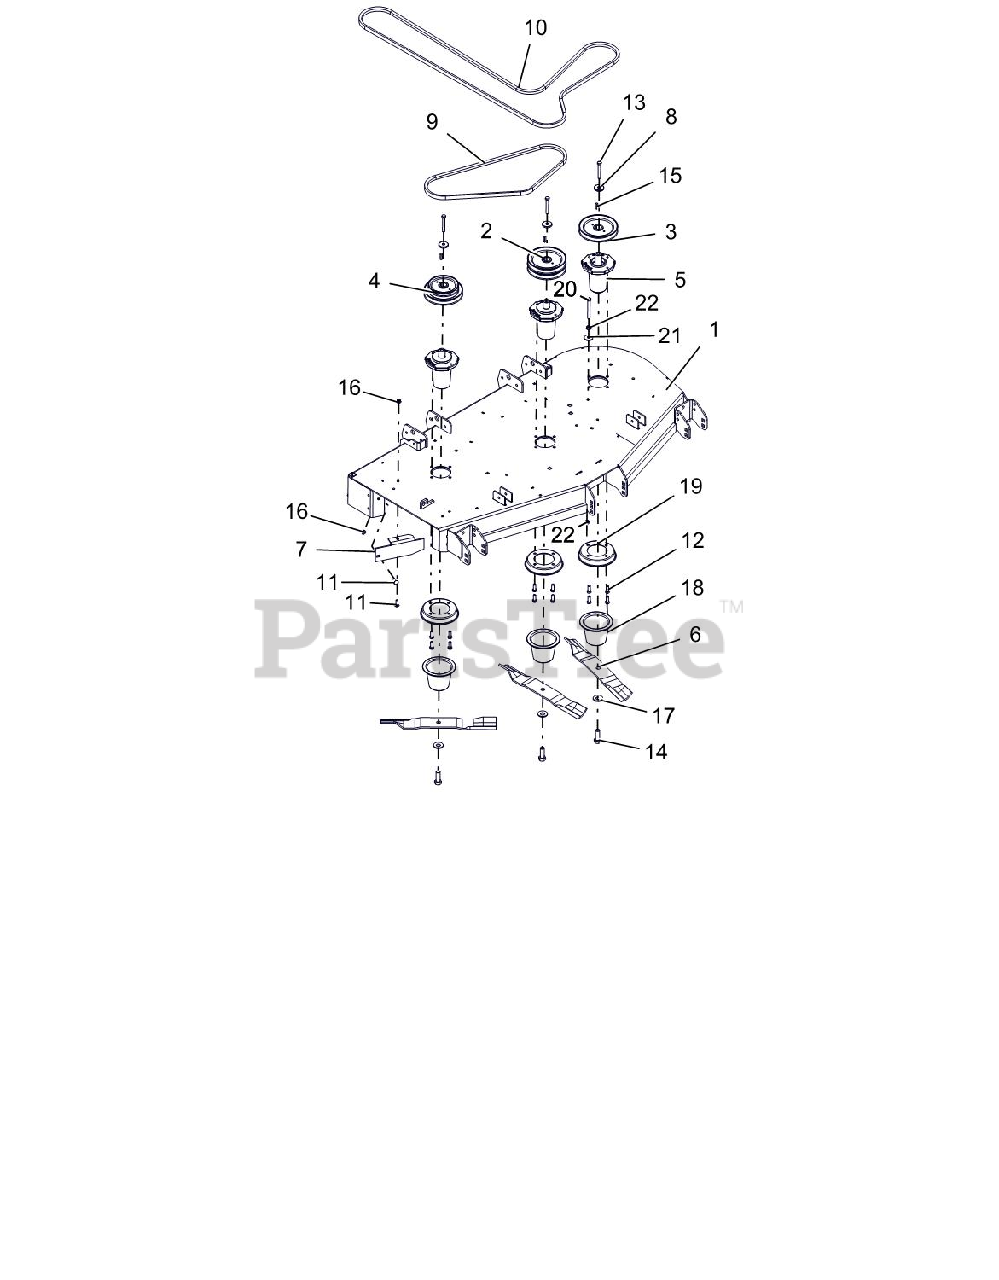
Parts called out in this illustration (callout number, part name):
1	DECK, PT152 W/SAFETY DECALS
2	PULLEY, DOUBLE
3	PULLEY, SINGLE-1"ID X 6" OD
4	PULLEY, DBL-1"IDX6.00"&4.75"OD
5	ASM, MAINT FREE SPINDLE
6	BLADE, 18.00" MOWER (HI-LIFT)
7	52" DISCHARGE BAFFLE - RED
8	RETAINER, SHEAVE
9	V-BELT, B-COGGED
10	BELT, B-SECTI0N EPDM RAW EDGE
11	@BLT-RDHDSQNK .31-18X1.00 G5YZ
12	BLT-HEX .38-16X1.0 GR8 YZ EP30
13	BLT-HEX .38-16X2.75 GR8 YWZC
14	BLT-HEX .62-18X1.75 GR8 YWZC
15	KEY, SQ .25X.25X1.00 RC 40-50
16	@NUT-LK-NYL-FLG .31-18 YWZC
17	WSHR-BLVL .669X1.535X.138
18	GUARD, SPINDLE LOWER
19	GUARD, SPINDLE TOP
20	@BLT-HEX .38-16X3.50 GR5 YWZC
21	WSHR-FL-STL .406X1.375X.135 YZ
22	@NUT-SPNLK-FLG .375-16 YWZC
